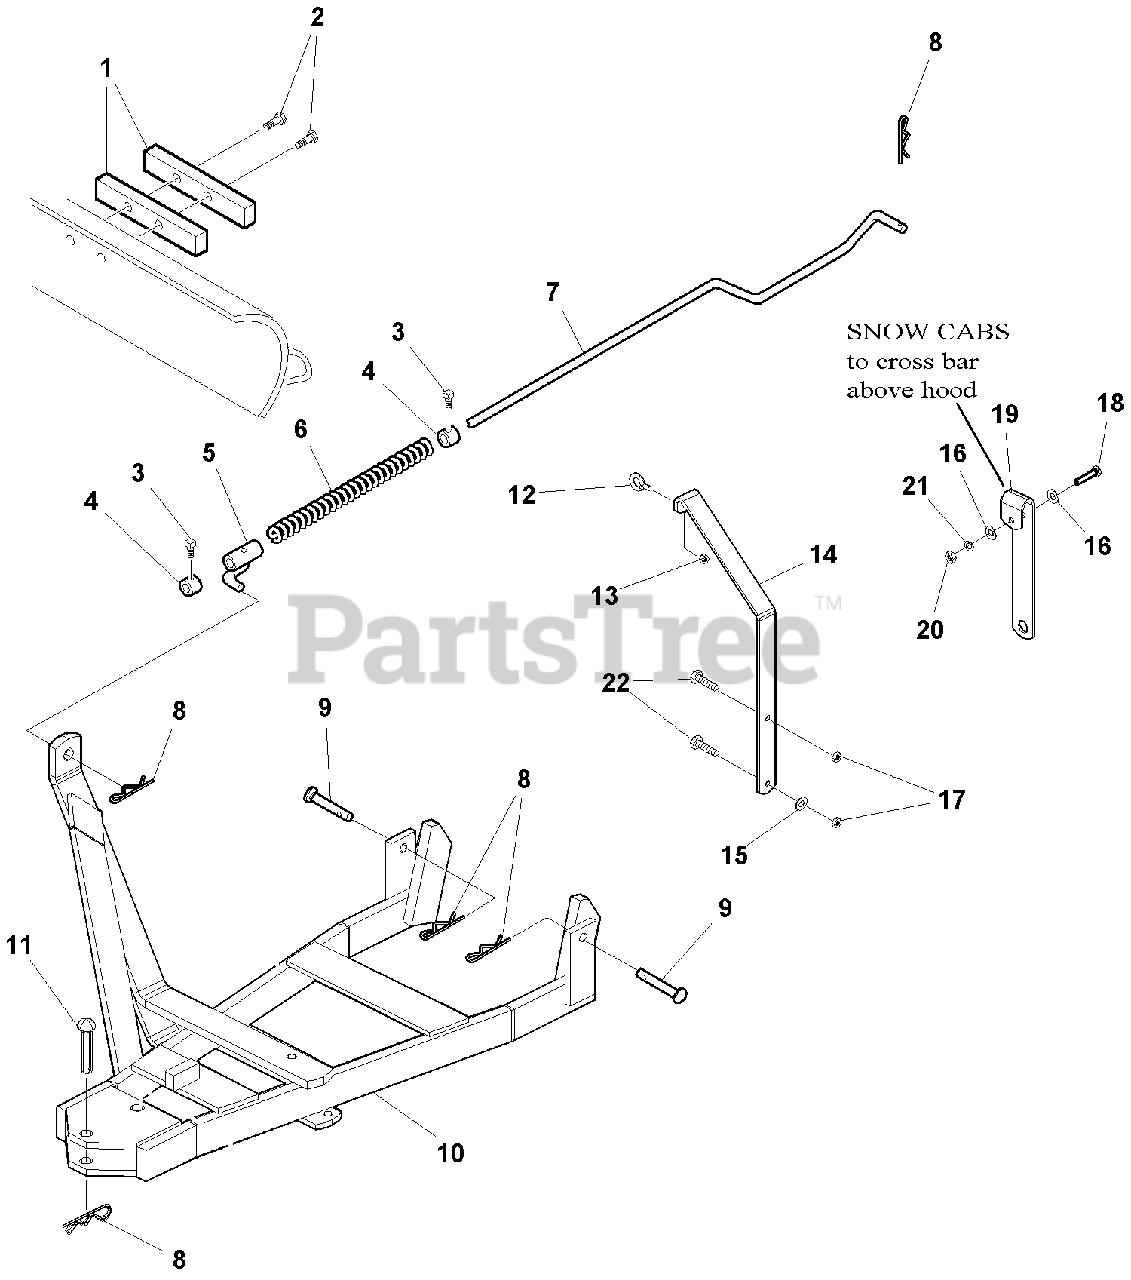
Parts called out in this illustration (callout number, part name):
1	BAR
2	CAPSCREW, Taptite, 5/16-18 x 1
3	SCREW, Set, 5/16-18 x 1/2
4	COLLAR
5	GUIDE ASSEMBLY
9	PIN
10	PUSH BAR ASSEMBLY
13	NUT, Hex, Centerlock, 1/4-20
14	BRACKET
15	WASHER
17	NUT, Whizlock, 5/16-18
18	CAPSCREW, Hex Head, 5/16-18 x 1-1/2
19	BRACKET
20	NUT, Hex, 5/16-18
21	LOCKWASHER, 5/16
22	CAPSCREW, Hex Head, 5/16-18 x 1
